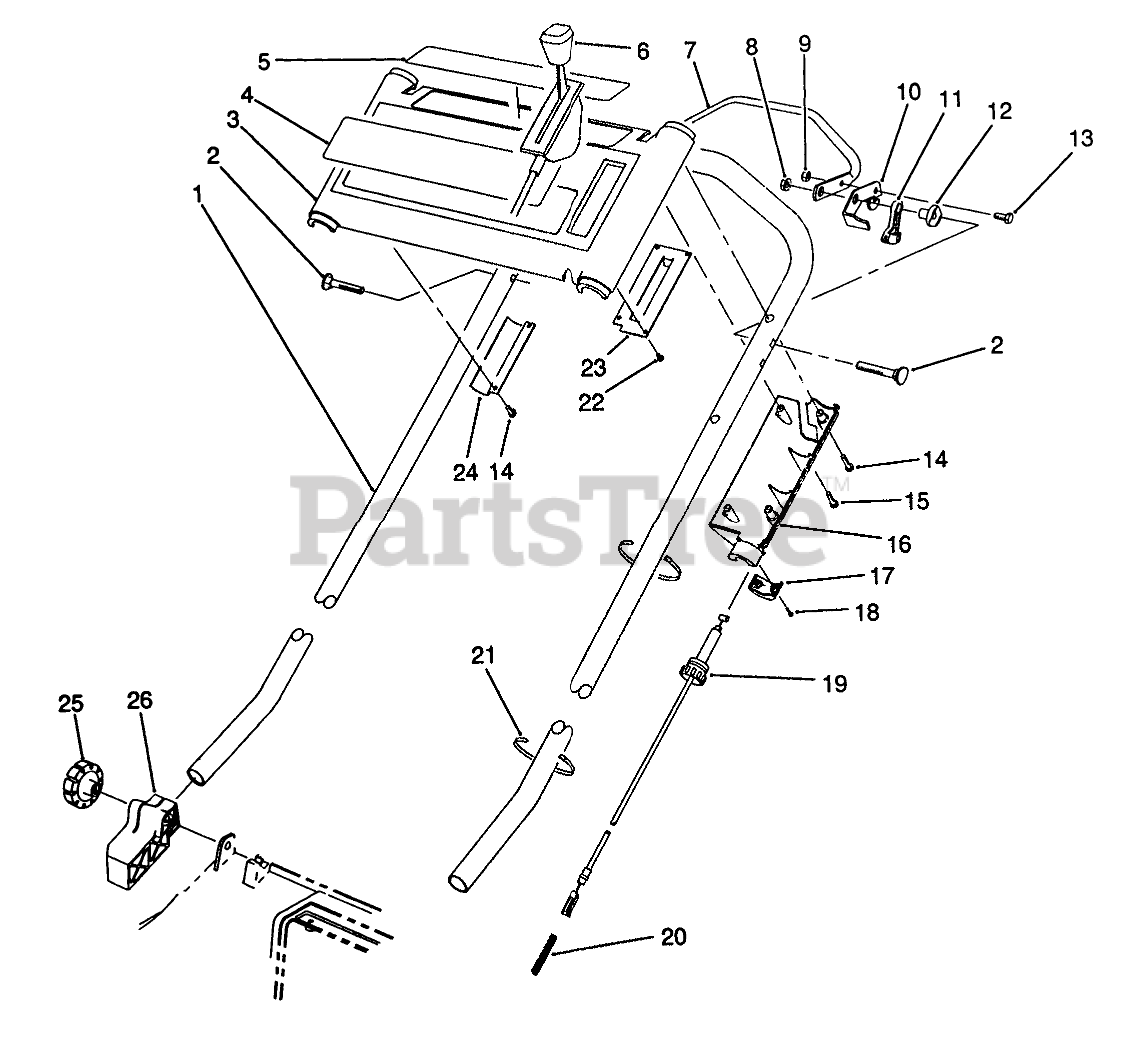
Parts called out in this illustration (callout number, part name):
1	Handle
2	SCREW-HANDLE
3	CONTROL PANEL W/DECAL
4	DECAL - TORO
5	DECAL - PANEL DANGER
6	THROTTLE CONTROL
7	CONTROL BAR
8	NUT-LOCK, NI
9	NUT-LOCK, NI
10	CONTROL LEVER
11	LEVER-TRACTION
12	SPACER-SUPPORT
13	SCREW-HH
14	SCREW-PPH, PLASTITE
15	Screw
16	Cover-Throttle Lower
17	LOWER THROTTLE CAP
18	#4-14X.62 PLASTITE SCW
19	TRACTION CABLE
20	SPRING-COMPRESSION
21	TIE-CABLE
22	#6-19X.25 PLASK FORM SC
23	THROTTLE PLATE
24	Bracket-Panel
26	MOUNT-HANDLE, LH
